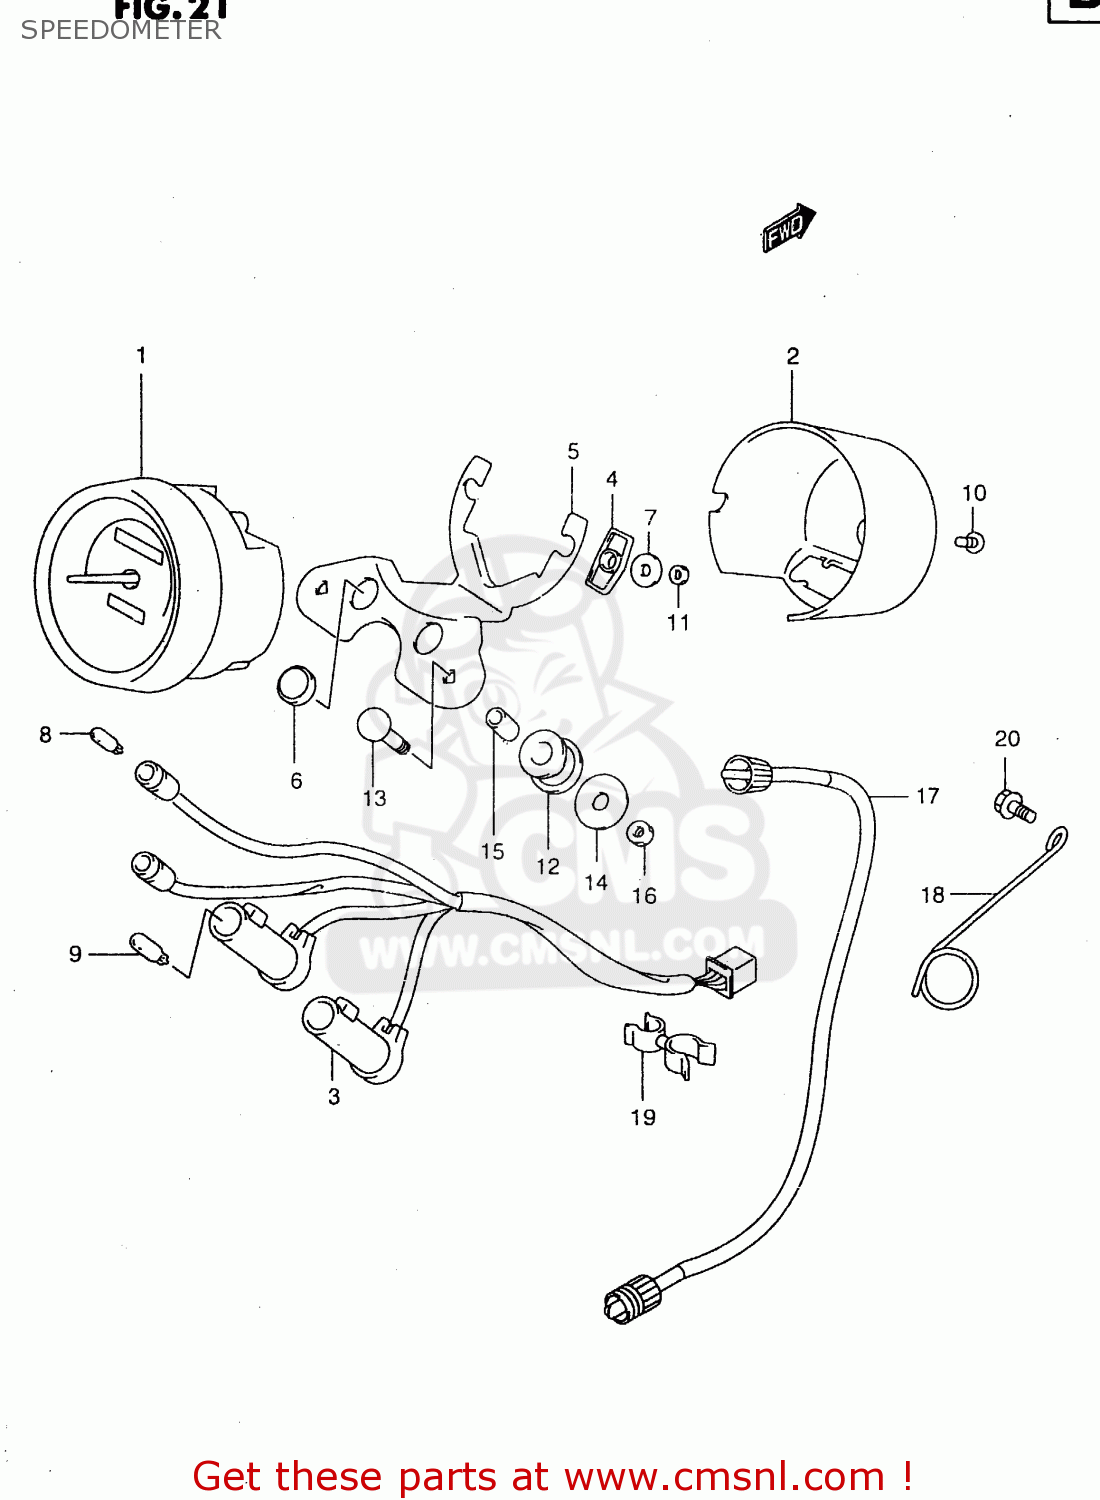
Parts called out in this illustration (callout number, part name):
1	SPEEDOMETER
2	COVER,UNDER(CHROMUN)
3	SOCKET ASSY
4	CUSHION,DAMPER
5	BRACKET,METER
6	LENS(GREEN)
7	WASHER(5.2X16X1)
8	BULB(12V3.4W,T10)
9	BULB(12V1.7W,T6.5)
10	SCREW
11	NUT
12	CUSHION,METER BRACKET
13	BOLT(6X30)
14	WASHER(6.5X28X1.6)
15	SPACER(6.5X10X15.7)
16	NUT 6MM
17	CABLE ASSY,SPEEDOMETER
18	GUIDE,SPEEDOMETER CABLE
19	CLIP
20	BOLT
